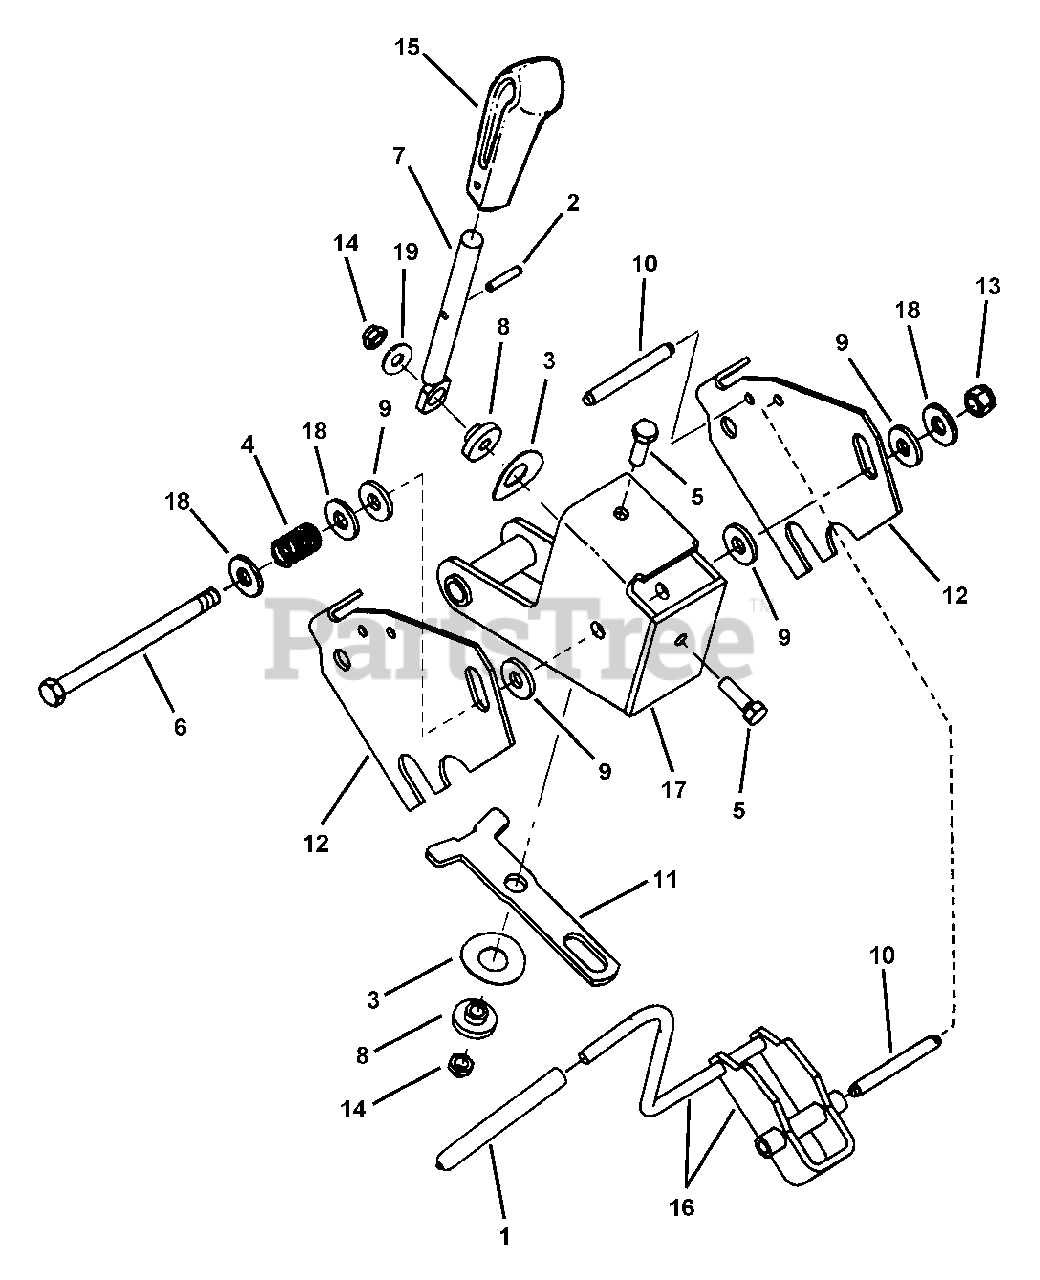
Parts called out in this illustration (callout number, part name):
1	GRIP, Vinyl
2	PIN, 3/16 x 1" Roll
3	WASHER, 5/8" I.D., 1-1/4" O.D.Bellville
4	SPRING, Compression
5	BOLT, 5/16-18 X 1 GD5 YZ
6	BOLT, 3/8-16 X 5" GD5 YZ
7	LEVER
8	BUSHING
9	WASHER, Slipper
10	PIN, Shoulder
11	CAM, Track
12	PLATE, Speed, Accutrack
13	NUT, 3/8-16 HEX NYLON LOCK
14	NUT, 5/16-18 Hex Top Lock, Grade B
15	HANDLE, Shift Lever
16	HANDLE, Weldment
17	TRACK, Welded
18	WASHER, 3/8" USS
19	WASHER, .33 x .88 x .09 Flat
